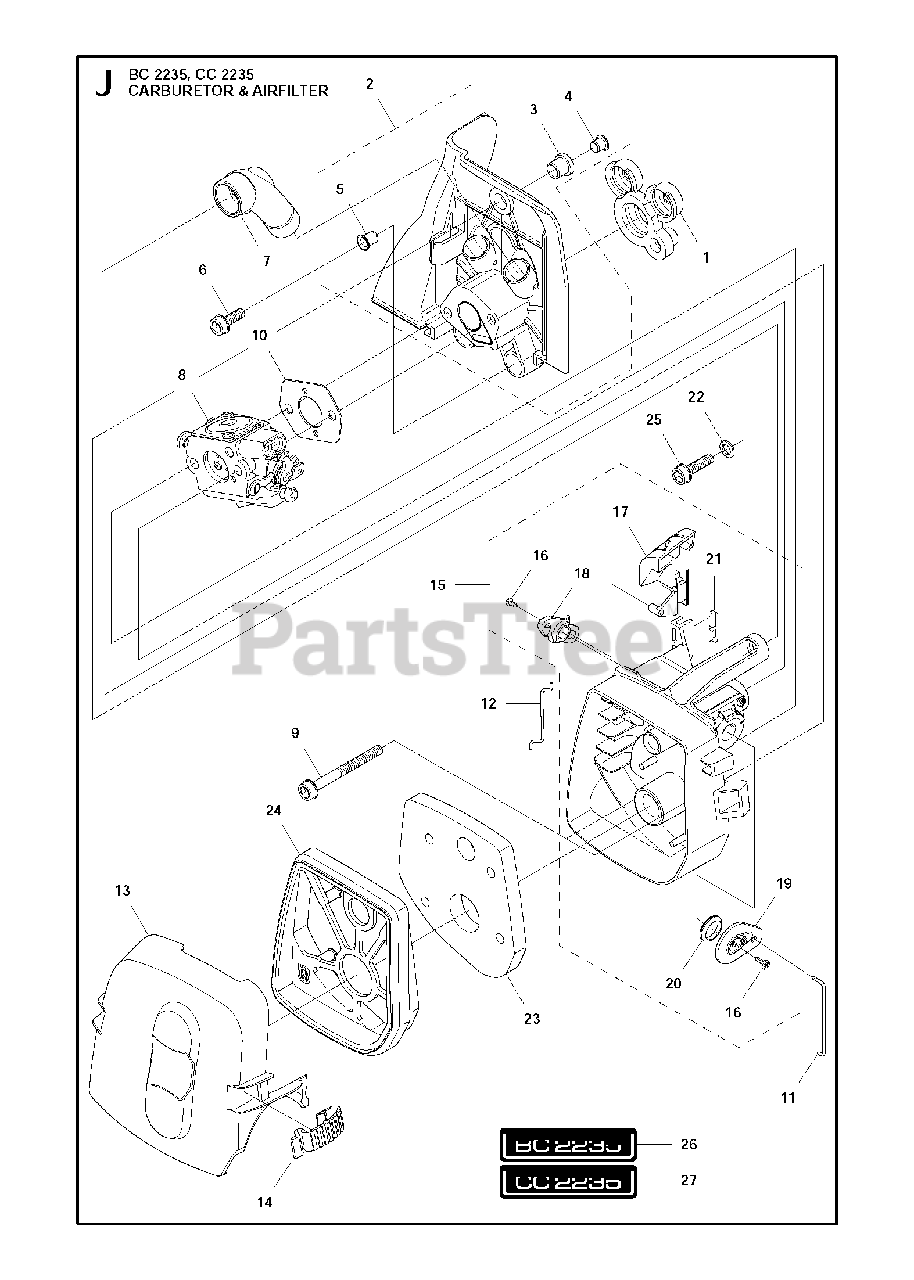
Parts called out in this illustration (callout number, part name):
2	PARTITION
3	SLEEVE
4	SLEEVE
5	SLEEVE
8	CARBURETOR
11	THROTTLE ROD
12	THROTTLE ROD
13	COVER AIR FILTER
15	FILTER HOLDER
16	SCREW
17	CHOKE CONTROL
18	CHOKE LEVER
19	LEVER
20	BELLOWS
21	RAIL
23	AIR FILTER
